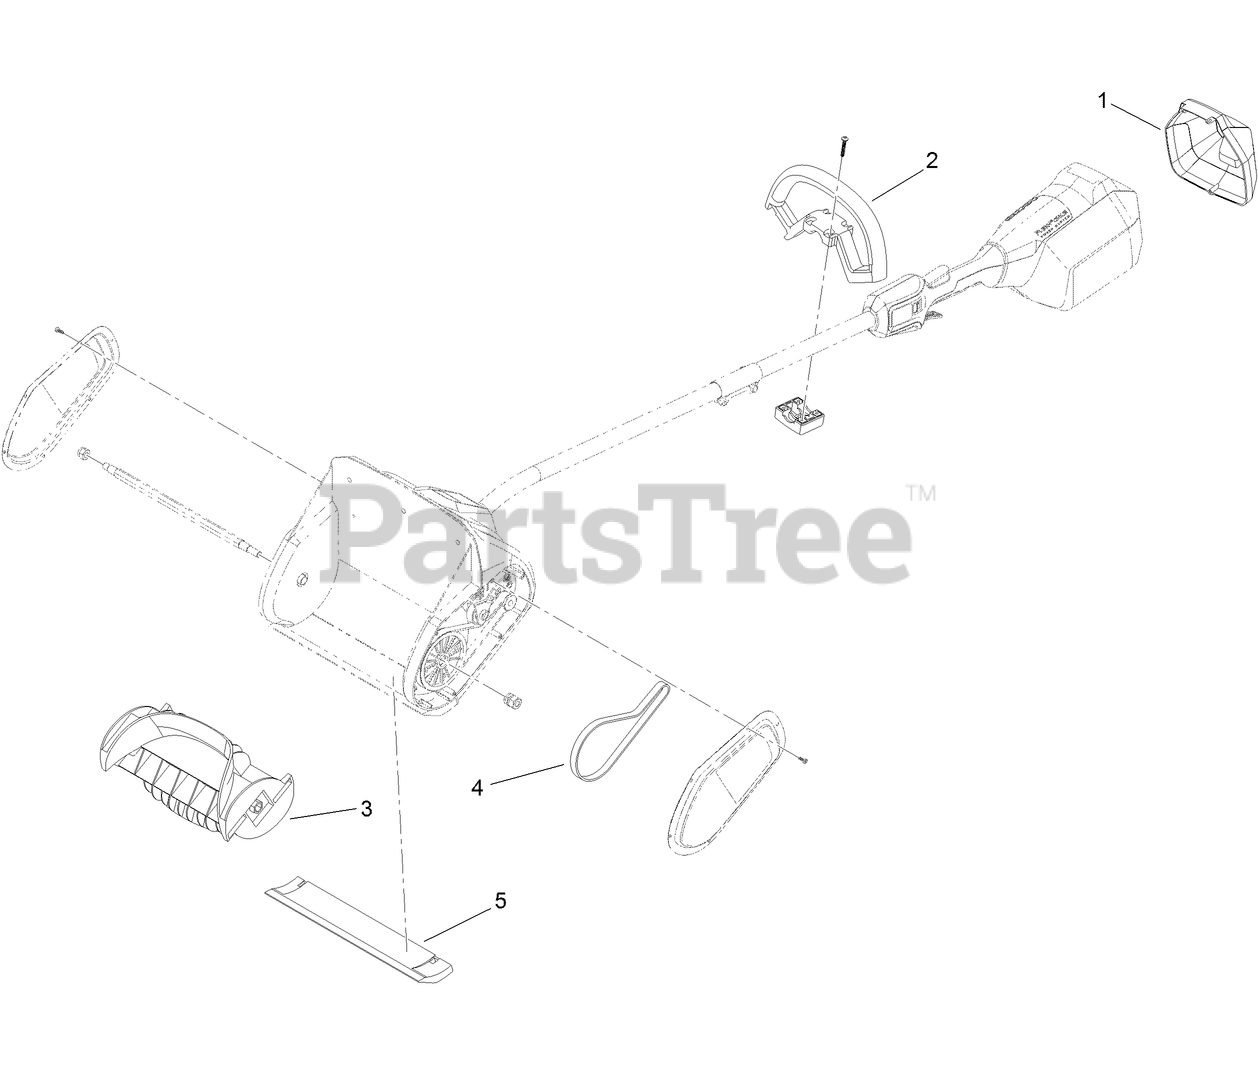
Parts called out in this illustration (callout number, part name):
1	COVER-BATTERY
2	HANDLE-TRIMMER
4	BELT-DRIVE
5	SCRAPER
